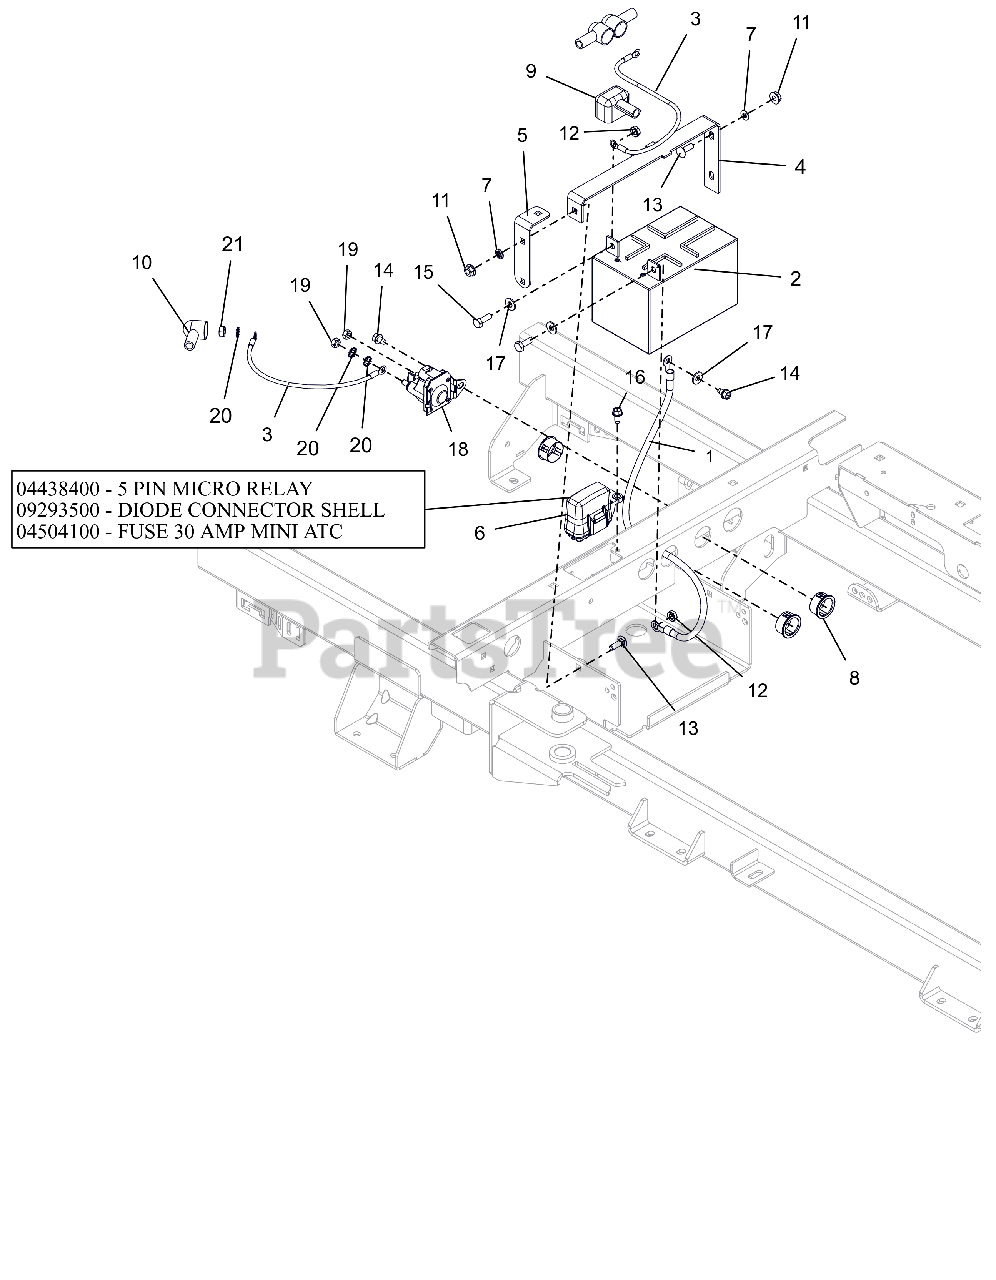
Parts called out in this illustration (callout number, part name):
1	CABLE-NEGATIVE BATTERY 24.00"
2	BATTERY, 12V 12A-190CCA
3	CABLE,POS W/2 1/4 RING 15.0 LG
4	BRKT, BATTERY HOLD-DOWN
5	BRKT, BATTERY HOLD DOWN
6	HARNESS, WIRE-4POS KEY IKON/ZT
6	RELAY,MICRO5 TERML W/RESISTOR
6	DIODE, CONNECTOR SHELL
6	FUSE,30 AMP MINI-ATC
7	NUT-PUSH .25X.50 O.D.
8	BSHG, PANEL SNAP .937X1.11X.56
9	INSULATOR
10	BOOT, EYELET TERMINAL
11	NUT-LK-TOP-FLG .250-20 GF ZCC
12	NUT-KEPS .250-20
13	BLT, RHSN .25-20X.750 G5 ZCC
14	SCR,TAP .25-20X.375 HWH TR ZCC
15	BLT, HEX .25-20X.75 G5 ZCC
16	SCR-TAP .25-20X.50 HWH ZCC
17	WSHR,FLT .281X.625X.065 ZCC
18	SOLENOID, STARTER (SEALED)
19	NUT-STD M6-1.0 ZCC
20	WSHR,LK-EXT.262X.502X.026 ZCC
21	NUT-STD .250-20 G2 ZCC
